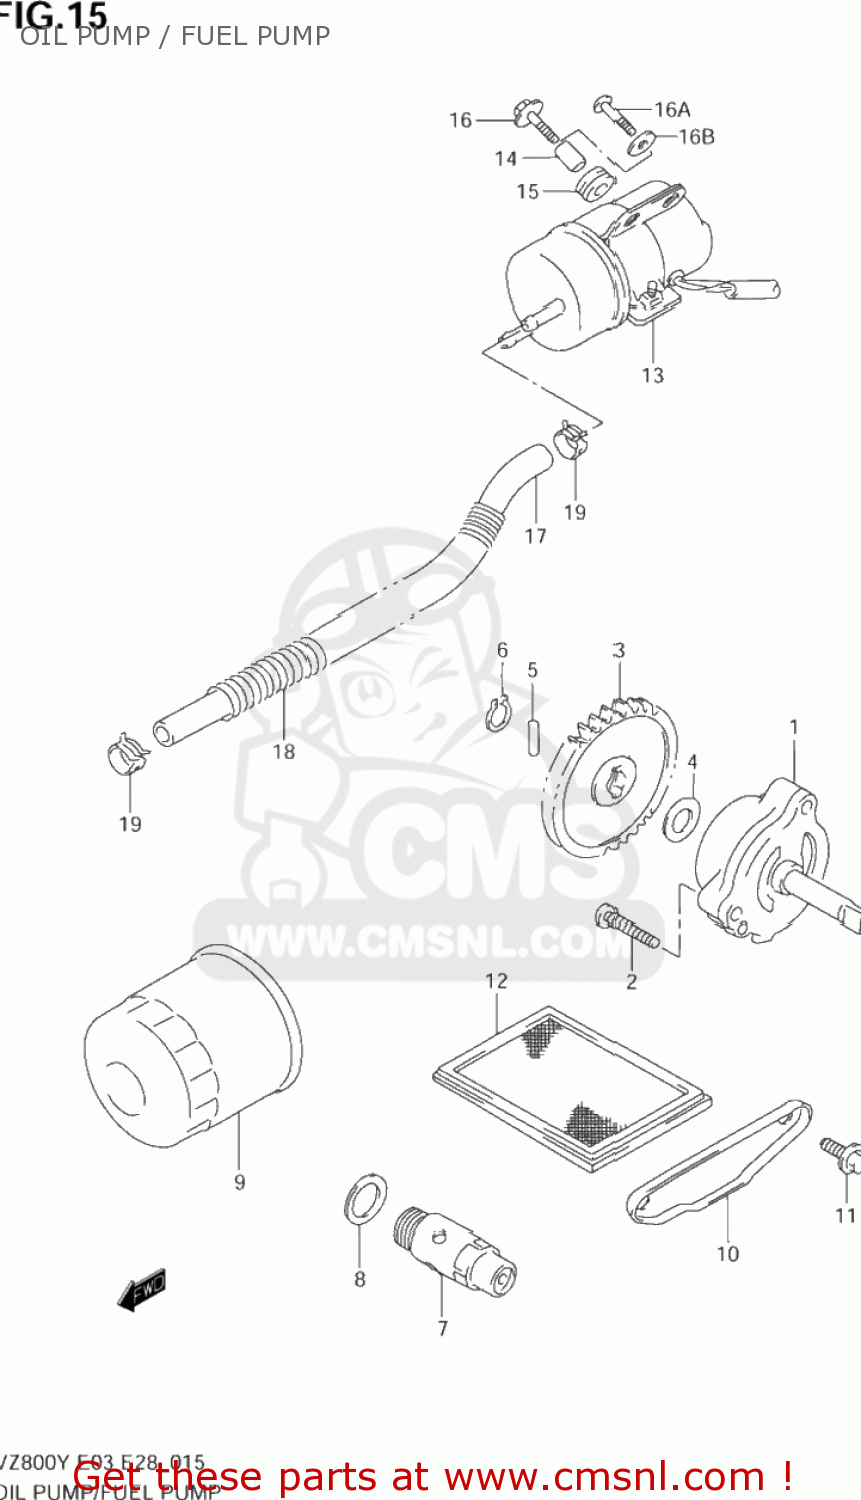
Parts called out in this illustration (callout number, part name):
1	PUMP ASSY,ENGINE OIL
2	SCREW
3	GEAR,OIL PUMP DRIVEN(NT:34)
4	SHIM(10X18X0.5)
5	PIN(4X15.8)
6	CIRCLIP,10MM
7	VALVE ASSY,OIL RELIEF
8	GASKET(16X22X2) (NAS)
9	FILTER ASSEMBLY,ENGINE OIL
10	CAP,OIL STRAINER
11	BOLT 6X12
12	STRAINER,ENGINE OIL
13	PUMP ASSY,FUEL
14	SPACER(6.5X9X9)
15	CUSHION
16	BOLT 6X20
16A	SCREW(6X20)
16B	WASHER(6.5X20X1.2)
17	HOSE(7X12X600)
18	SPRING
19	CLIP
